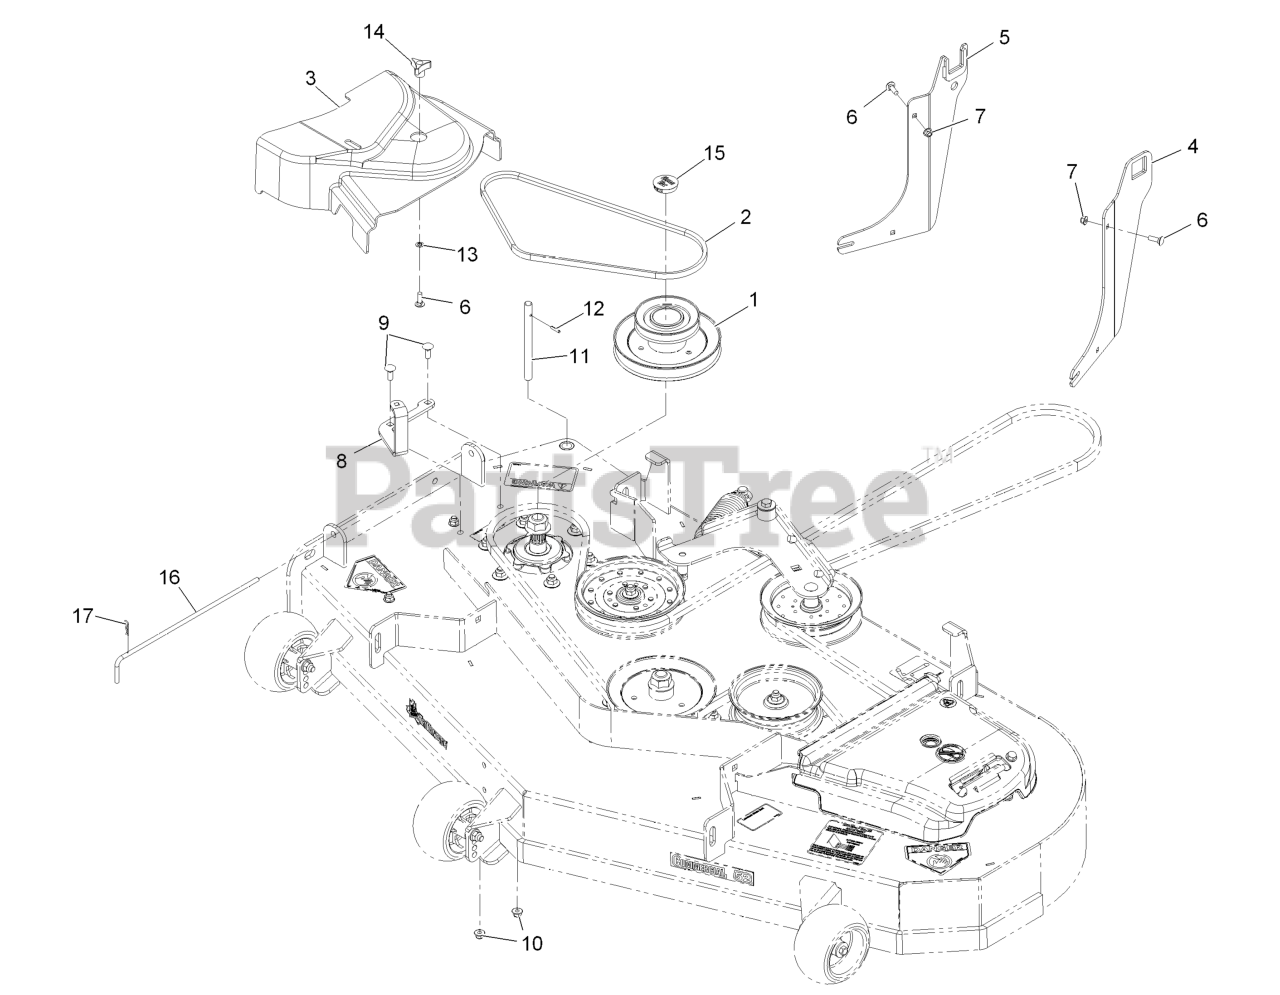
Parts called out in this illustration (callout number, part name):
1	JACKSHAFT-UV DRIVE 52 SPL
2	BELT-BLOWER
3	COVER-BELT, UV 52
4	BRACKET ASM, LH
5	BRACKET ASM, RH
6	BOLT-CARR
7	NUT-HF, NI
9	BOLT-CARR
10	NUT-HF, NI
11	SHAFT-CATCHER, GRASS
12	PIN-ROLL
13	RING-RETAINING, BOLT
14	KNOB-3 PRONG
15	PLUG, BLACK NYLON 1.75
16	PIN,CHUTE PIVOT
17	PIN-COTTER
